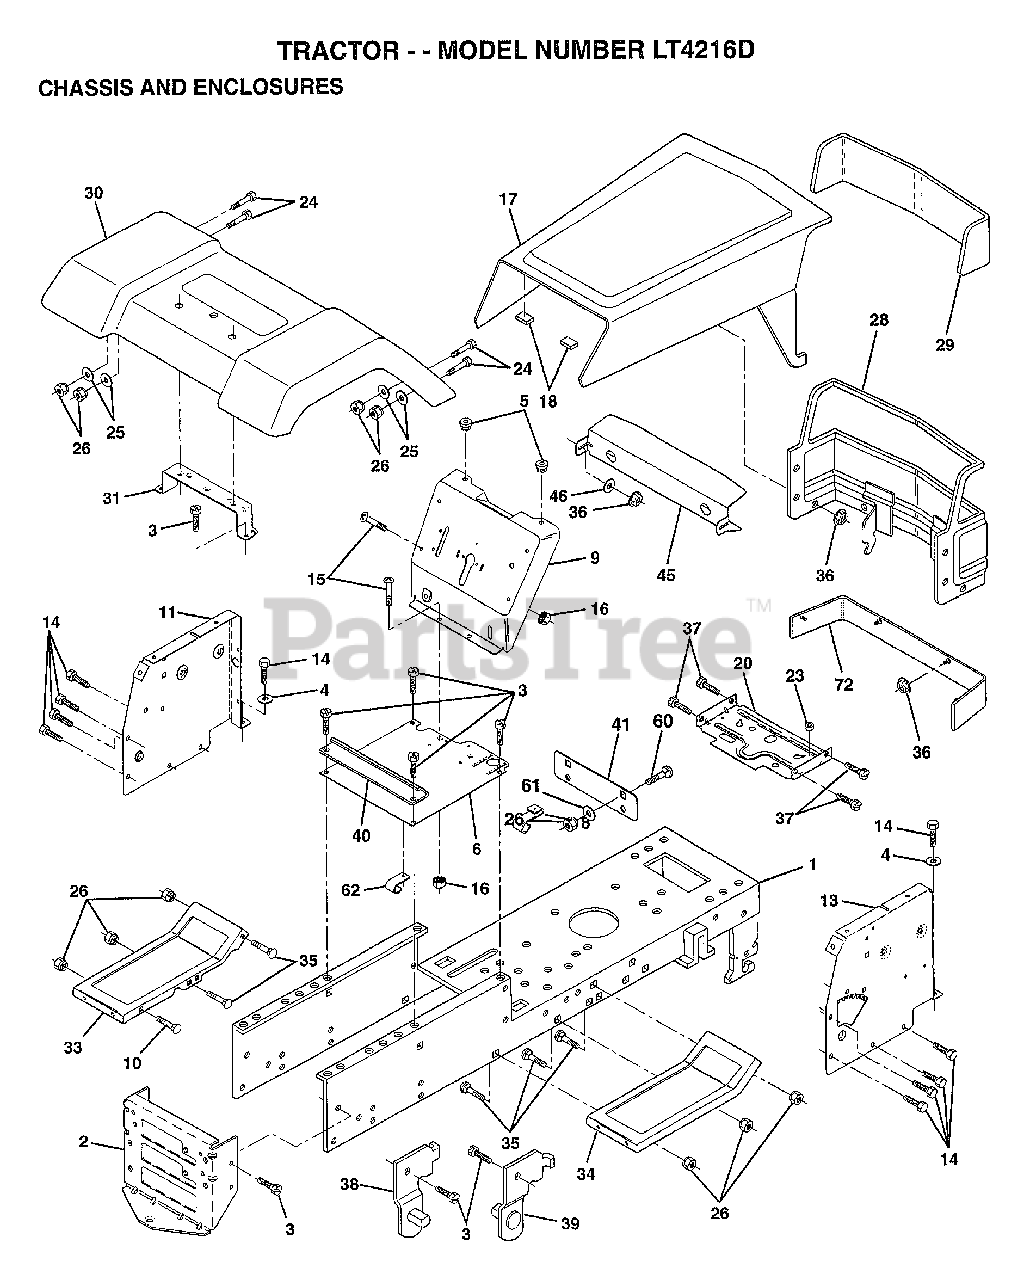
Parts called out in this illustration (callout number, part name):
1	CHASSIS.WLD.11GA
3	SCREW
4	WASHER
8	"CLIP,INSULATOR"
9	DASH.SLKSC.LT.1PC
11	DASH PANEL LH
14	SCREW LT
15	SCREW
17	HOOD/SD.PNLS.KGRO
20	PLATE.MTG.BTRY.TK
24	BOLT
25	WASHER
26	NUT
28	GRILLE.RALLY.BAR.
31	BRACKET SUPT FEND
33	FOOTREST.LH.LT/GT
34	FOOTREST.RH.LT/GT
35	BOLT
36	PAL NUT LT
37	SCREW LT
38	BRACKET ASM LH
39	BRACKET ASM RH
40	SPACER FENDER LT
41	PLATE EXTEN FEND
46	RETAINER
60	BOLT
61	WASHER
72	STRAP.GRILLE.PNT.
